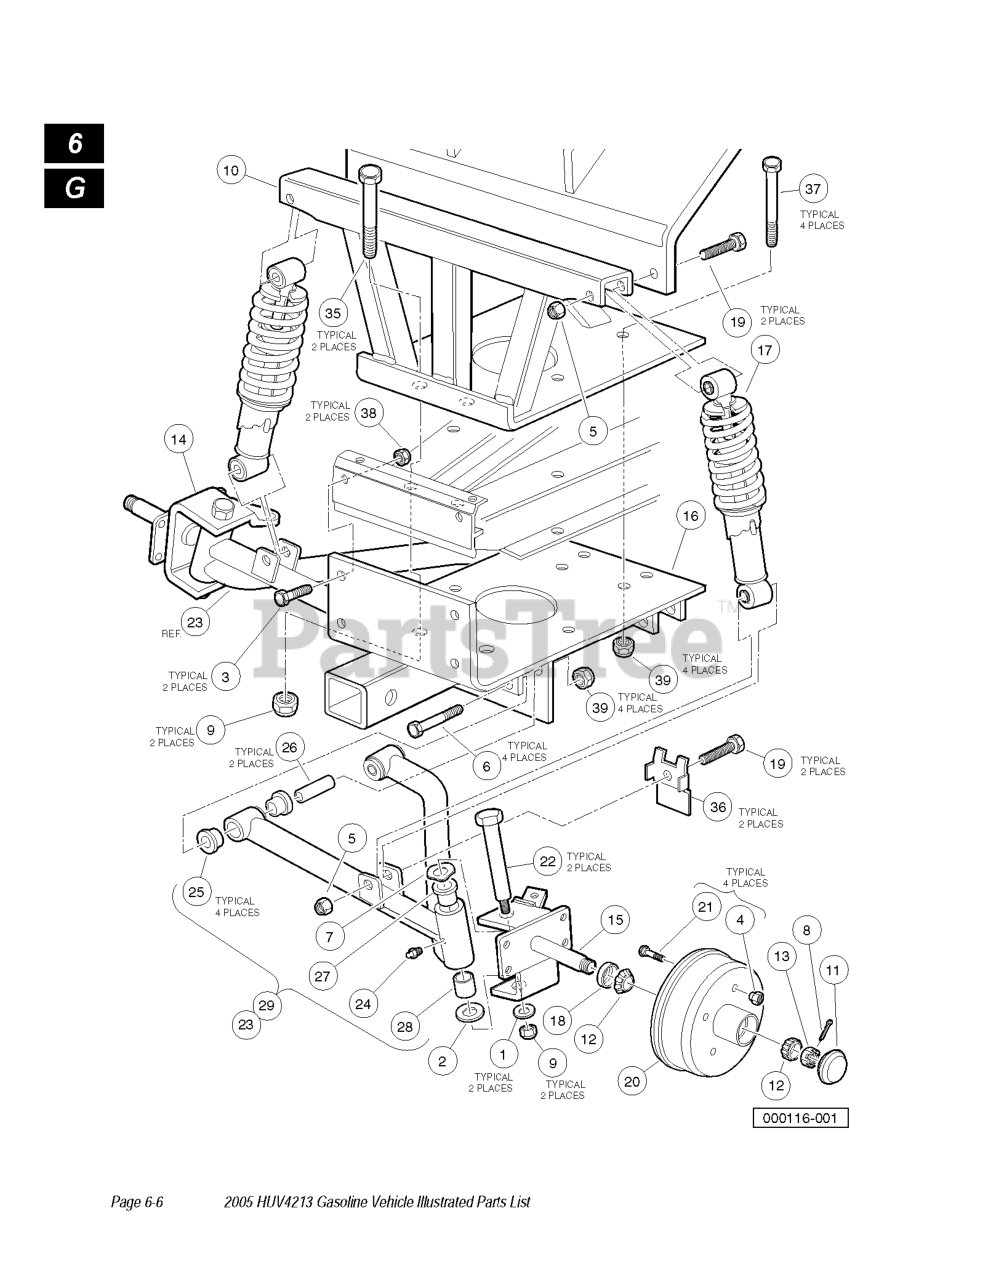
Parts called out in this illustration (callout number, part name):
1	WASHER, 1/2 TYPE A FLAT
2	BEARING THRUST
3	SCREW HEX CAP
4	NUT 1/2-20 LUG
6	SCREW, 3/8-16 X 2.75 HX HD CAP
7	WASHER, 1.125 OD WAVE
8	PIN-COTTER - .312 X 1.25"
9	LOCKNUT, 1/2-20 NYLON INSERT
10	SHOCK TOWER
11	DUST COVER
12	BEARING, TAPERED
13	NUT, 1.00-14 SLOTTED HEX JAM
14	ASM, SPINDLE - RH
15	ASM, SPINDLE - LH
16	SUSPENSION MEG PLATE
17	SHOCK ABSORBER, COIL OVER
18	SEAL, DOUBLE LIP
19	SCREW, 7/16-14 X 2.50 HEX CAP
22	KING PIN BOLT ASM
23	RIGHT A-ARM ASM
24	FITTING, 1/4-28 THRD FRM GREAS
25	BUSHING, URETHANE
26	A-ARM SLEEVE
27	BUSHING, FLANGED BROZE
28	BUSHING BRONZE SPINDLE
29	LEFT A-ARM ASM
30	FITTING, 1/4-28 THRD FRM GREAS
31	BUSHING, URETHANE
32	A-ARM SLEEVE
33	BUSHING, FLANGED BROZE
34	BUSHING BRONZE SPINDLE
35	SCREW, 1/2-20 X 5.0 HEX CAP
36	STEERING STOP MTG PLATE
37	BOLT, HEX HEAD
38	LOCKNUT, 5/16-18 NYLON INSERT
39	LOCKNUT, 3/8-16 HEX
